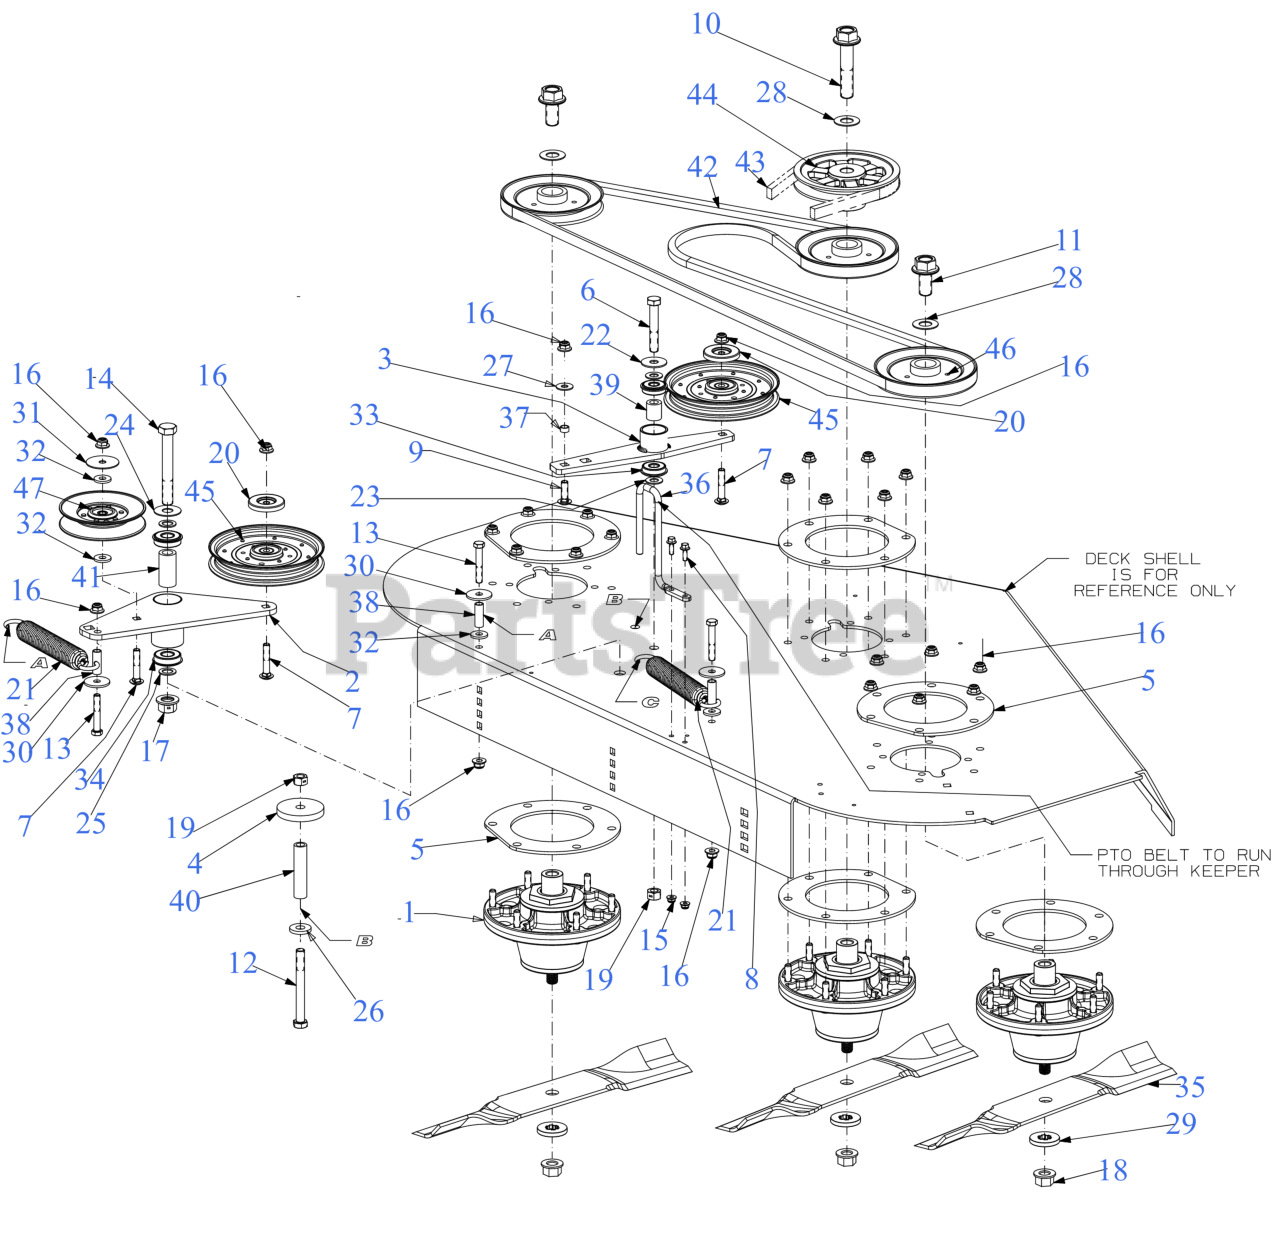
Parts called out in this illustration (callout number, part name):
1	SPINDLE ASSEMBLY
3	IDLER BRACKET
4	SPACER PLATE
5	SPINDLE SUPPORT BRACKET TOP/BTM
6	SCREW-HEX 1/2-13 x 3.00
7	CARRIAGE BOLT 3/8-16 x 2
8	SCREW 1/4-20 x .75 GR5
9	CARRIAGE BOLT 3/8-16 X1.25 GR5
10	CAP SCREW-HHFLG 3/4-10 X 3.50 GR8
11	CAP SCREW-HHFLG 3/4-10 X 1.50 GR8
12	SCREW 1/2-13 x 4.5 GR 5
13	SCREW 3/8-16 x 2.25 GR5
14	SCREW 5/8-18X4.5 GR5
15	FLANGE LOCK NUT
18	FLANGE NUT - 5/8-18 GDE 8
19	HEX NUT CTR LK 1/2-13
20	PULLEY CAP
21	SPRING 1.25" DIA x 8.5" LONG
22	WASHER .51 x 1.5 x .07
23	FLAT WASHER .510 x .995
24	FLAT WASHER-.63IDX1.595ODX.62
25	FLAT WASHER
26	FLAT WASHER .531 x 1.25 x .181
27	WASHER-.395 x 1.0 x .62
28	FLAT WASHER
29	FLAT WASHER - SPECIAL
30	FLAT WASHER .406X1.500X.105
31	HUB CAP WASHER .406 x 1.92 x .060
32	FLAT WASHER .406ID X1.0 OD
33	ROLLER BEARING .5X1.37X.44
34	BALL BEARING W/RET
35	19" BLADE (HI LIFT)
35	Cub Cadet 54" HI LIFT BLADE SET
35	LOW-LIFT 19"BLADE (54"DECK)
35	BLADE- HI LIFT 19.0 XTREME
35	BLADE-19"MULCH 54"
35	19" XTREME BLADE
39	SPACER 0.51 x 0.88 x 1.00
41	SPACER 0.63 x 1.00 x 2.01
42	BELT-B SECTION 119.45"
43	V-BELT B SEC x 101.1
44	PULLEY-6.96 OD x .750 ID
45	IDLER PULLEY
46	SPINDLE PULLEY 6"
47	IDLER PULLEY 5.06 OD
